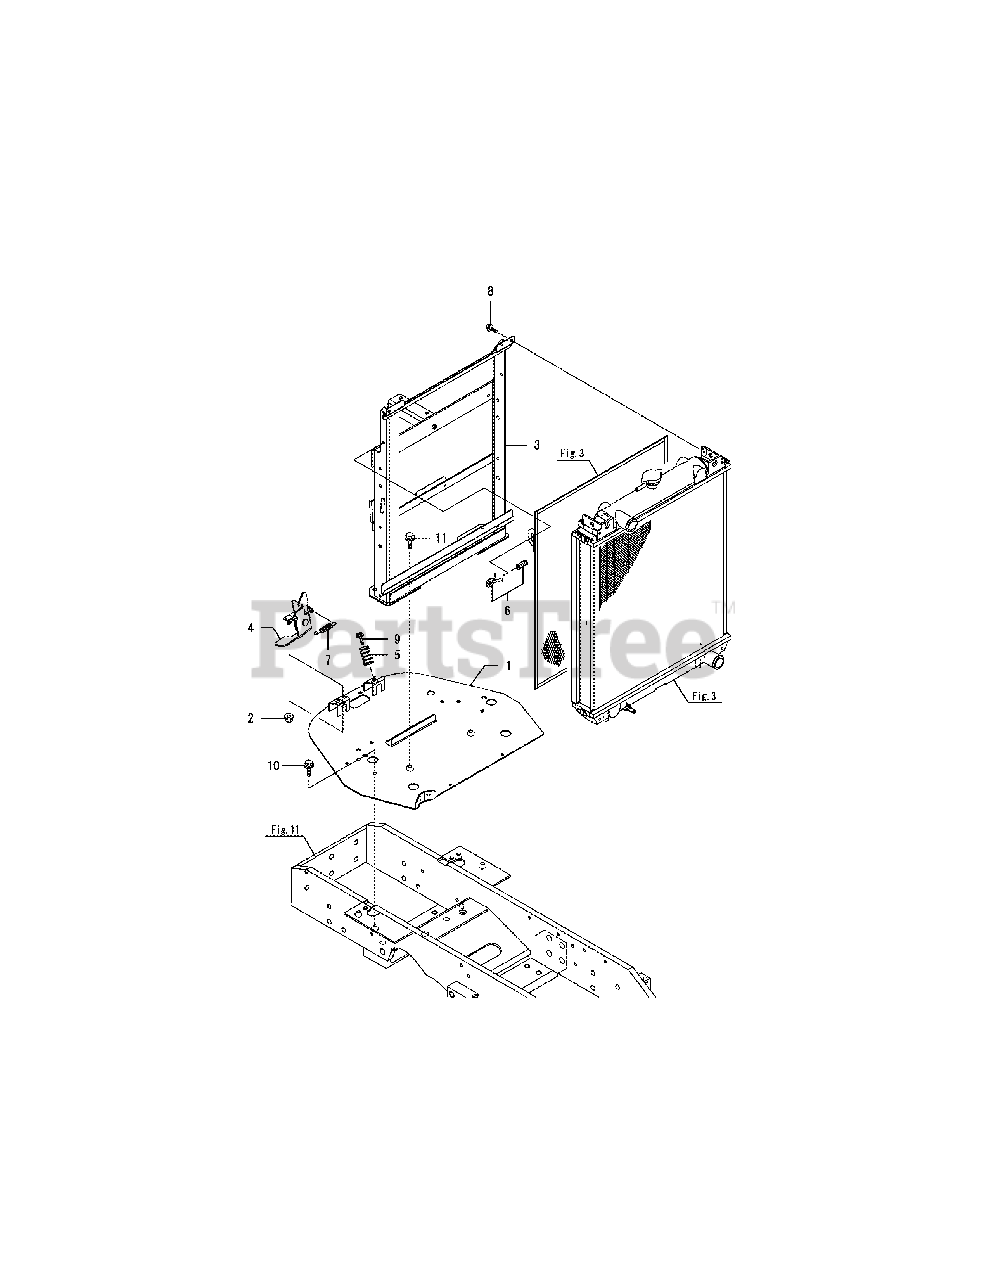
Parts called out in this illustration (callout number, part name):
1	BRACKET ASSY, RADI
2	NUT W/WASHER 8
3	FRAME ASSY, FRONT
4	BONNET LOCK CMP
6	LOCK COMP.,CAM
8	BOLT M 6X 20 PLATED
9	BOLT M 6X 20 PLATED
10	BOLT M 8X 20 PLATED
11	BOLT M 8X 20 PLATED
